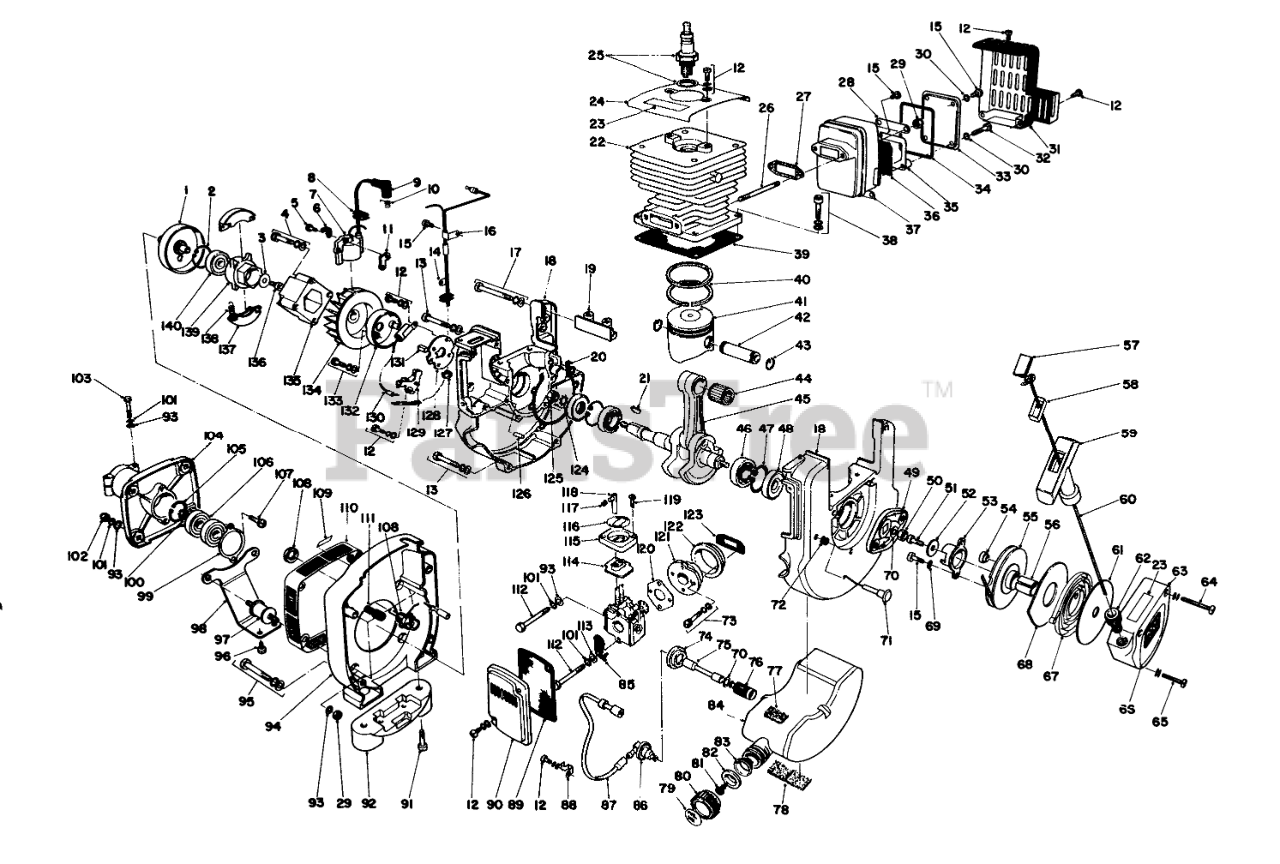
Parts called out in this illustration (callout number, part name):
1	Clutch Drum
2	Circlip
3	Washer
4	Hex Socket Hd. Bolt w/Washer
5	Screw
6	Clamp
7	Ignition Coil
8	Grommet
9	Cap-Spark Plug
10	Coil Spring-Plug Cap
11	Spacer
12	SCREW
13	Hex Socket Hd. Bolt w/Washer
15	Screw
16	Clamp
17	Hex Socket Hd. Bolt w/Washer
18	Crankcase Set
19	Muffler Support
20	Gasket-Crankcase
21	Woodruff Key
22	Cylinder
23	Decal-Hot Surface
24	CYLINDER COVER
25	Spark Plug
26	Stud Bolt
27	Gasket, Muffler
28	Washer
30	Washer
31	Muffler Cover
32	Screw
33	Muffler Lid
34	Gasket-Muffler Lid
35	Screen Holder
36	Screen
37	Muffler
38	Screen, Inlet
39	Gasket, Cylinder Base
40	Piston Ring
41	Piston
42	Piston Pin
43	Circlip, Piston Pin
44	Needle Bearing
45	Crankshaft Assembly
46	Bearing
47	Circlip
48	Oilseal
49	Ratchet Assembly
50	Locknut
51	Lever, Metering
52	Washer
53	Pawl Catcher
55	RECOIL DRUM
56	DRUM BSHG
57	Cap, Starter Handle
58	End Piece
59	Starter Handle
60	Starter Rope
61	Side Plate
62	Rope Guide
63	Starter Case
64	Screw w/Washer
65	SCREW
66	Decal-Toro
67	REWIND SPRING
68	SIDE PLATE (B)
69	Spring Washer
70	Washer
71	Choke Rod
72	Grommet
73	Hex Socket Hd. Bolt w/Washer
75	Fuel Pipe, Inner
76	Fuel Strainer
77	Cushion
78	Cushion
79	Decal Fuel Mix
80	Cap-Fuel Tank
81	Check Valve
82	CHECK VALVE HOLDER
83	Rubber Ring
84	Fuel Tank
85	Choke Shutter
86	Connector
87	Fuel Pipe, Outer
88	Clamp
89	Air Filter
90	Cover, Air Cleaner
91	Screw
92	Cushion
93	WASHER
94	Fan Cover
96	Screw
97	Cushion
98	Bracket
99	Bearing Retainer
100	Circlip
101	Washer
102	Capnut
104	Case, Clutch Drum
105	Circlip
106	Ball Bearing
107	Screw
108	Switch
109	STOP SWITCH DECAL
110	Dust Seal
113	CHOKE SHUTTER SPACER
114	Grommet
115	Frame
116	Decal Guide
117	Knob
118	Adjuster
119	Screw
120	CARB PACKING GASKET
121	Insulator
122	Grommet
123	CARB GASKET
124	Lockwasher
126	Knockpin
128	Stator Plate
129	CONTACT POINT
130	CONDENSER
131	Oil Pad
132	Breaker Cover
133	Screw w/Washer
134	Flywheel
135	Coupler
136	Hex Socket Hd. Bolt
137	Clutch Shoe
138	CLUTCH SPRING
139	Clutch Boss
140	Ball Bearing
